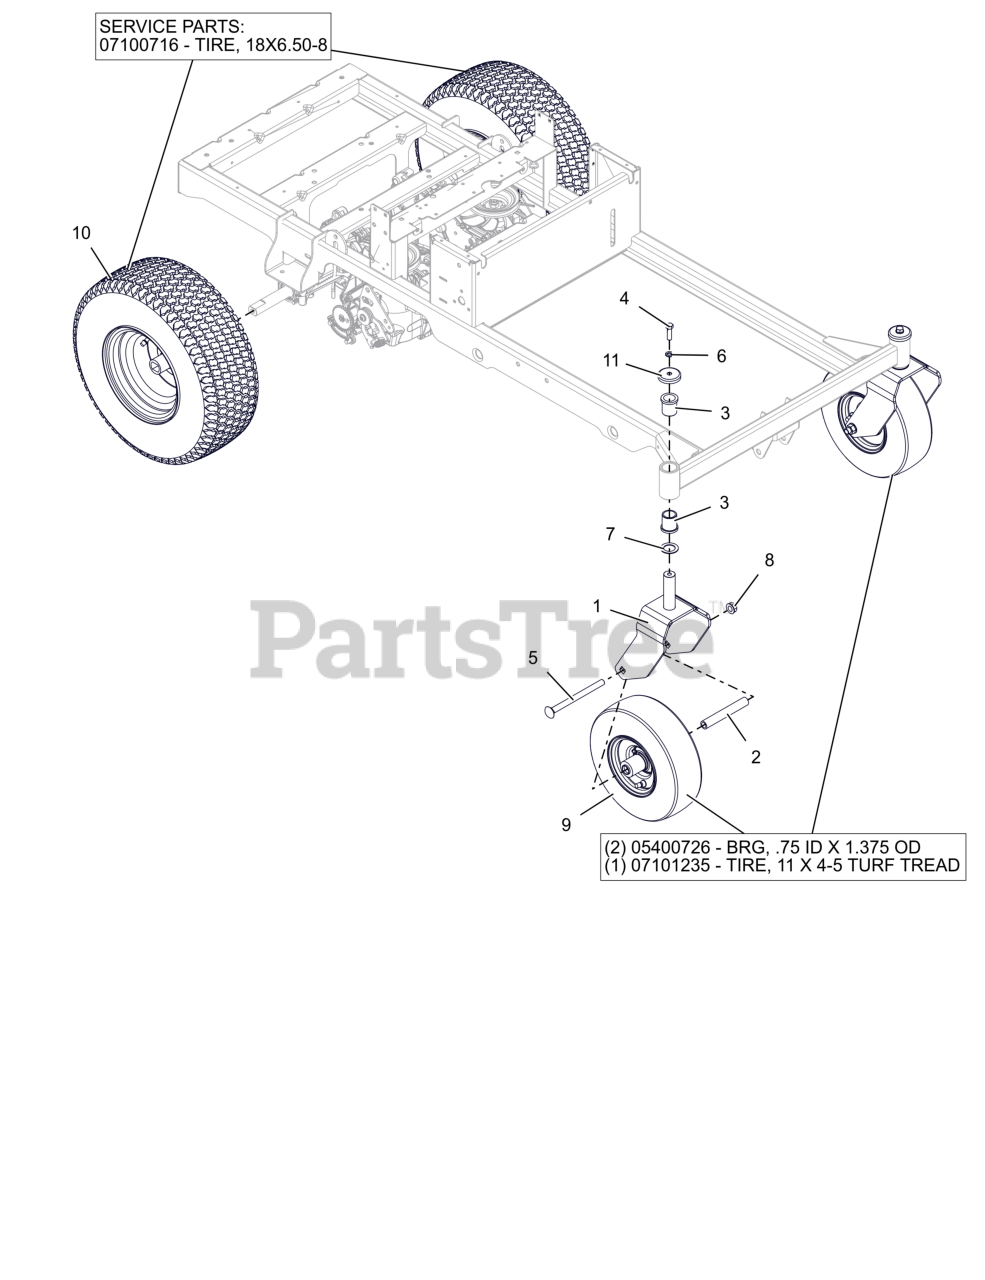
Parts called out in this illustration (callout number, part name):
1	WLDMT- CASTER FORK
2	SPACER, ROLLED WHEEL
3	BSHG-FLG 1.00X1.25X1.50X1.50
4	BLT- HEX .38-16X1.25 G5 ZB500
5	BLT, RHSN .50-13X6.50 G5 ZCC
6	WSHR-LK-REG .375X.094 ZB500
7	WSHR-HRD-THRS 1.007X1.542X.062
8	NUT-LK-CTR-FLG .500-13 GG ZCC
9	ASM, WHL/TIRE 11X4.00-5
9	BRG, .75 ID X 1.375 OD
9	LAWN TIRE FRONT, 11/4-5 TURF TREAD
9	VALVE STEM ASS'Y
9	TIRE TUBE, 11/4.0-5 4 PLY TR87 90 BENT VALVE
10	ASM, WHL/TIRE 18X6.50-8 DHUB
10	TIRE, 18X6.5-8
10	VALVE STEM ASS'Y
10	TIRE TUBE 18/6.50/8.50/9.50-8, 20/8.00/10.00-8 4 PLY TR13 STRAIGHT VALVE
11	SHIELD- AXLE BEARING BLK
